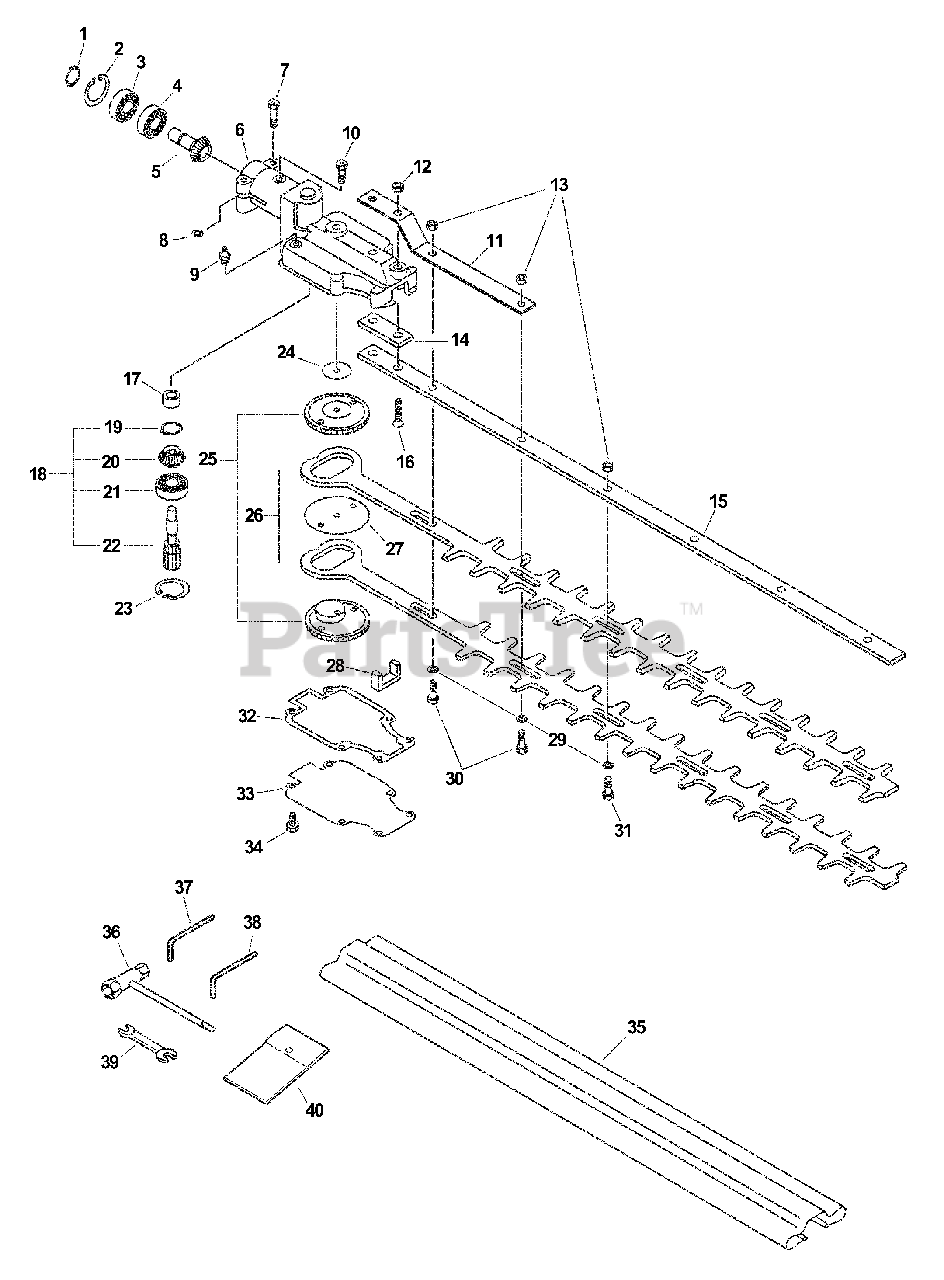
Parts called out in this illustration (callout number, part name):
1	RING, RETAINING - 24
2	RING, RETAINING - 12
3	BEARING, BALL - 6901Z
4	BEARING, BALL - 6901
5	GEAR
6	CASE, GEAR - UPPER
7	SCREW - 5X28
9	FITTING, GREASE
10	SCREW - 5X12
11	BRACKET, BLADE
12	LOCKNUT - 6
13	LOCKNUT - 6
14	PLATE
15	SUPPORT, BLADE
16	SCREW - 6X35
17	BEARING, NEEDLE
18	SPUR GEAR ASSY
19	RING, RETAINING
20	GEAR - BEVEL -- DRIVEN
21	BEARING, BALL - 6901
22	GEAR - SHAFT
23	RING, RETAINING - 24
25	GEAR - SPUR
26	BLADE, TRIMMER
28	SEAL, FELT
29	WASHER - 6
31	BOLT - 6
32	GASKET, GEAR CASE
33	LID, GEAR CASE
34	SCREW - 4X12
35	COVER, BLADE
36	T-WRENCH - 17X19mm
37	HEX KEY - 4mm
38	HEX KEY - 3mm
39	SPANNER - 8X10mm
40	BAG, TOOL
